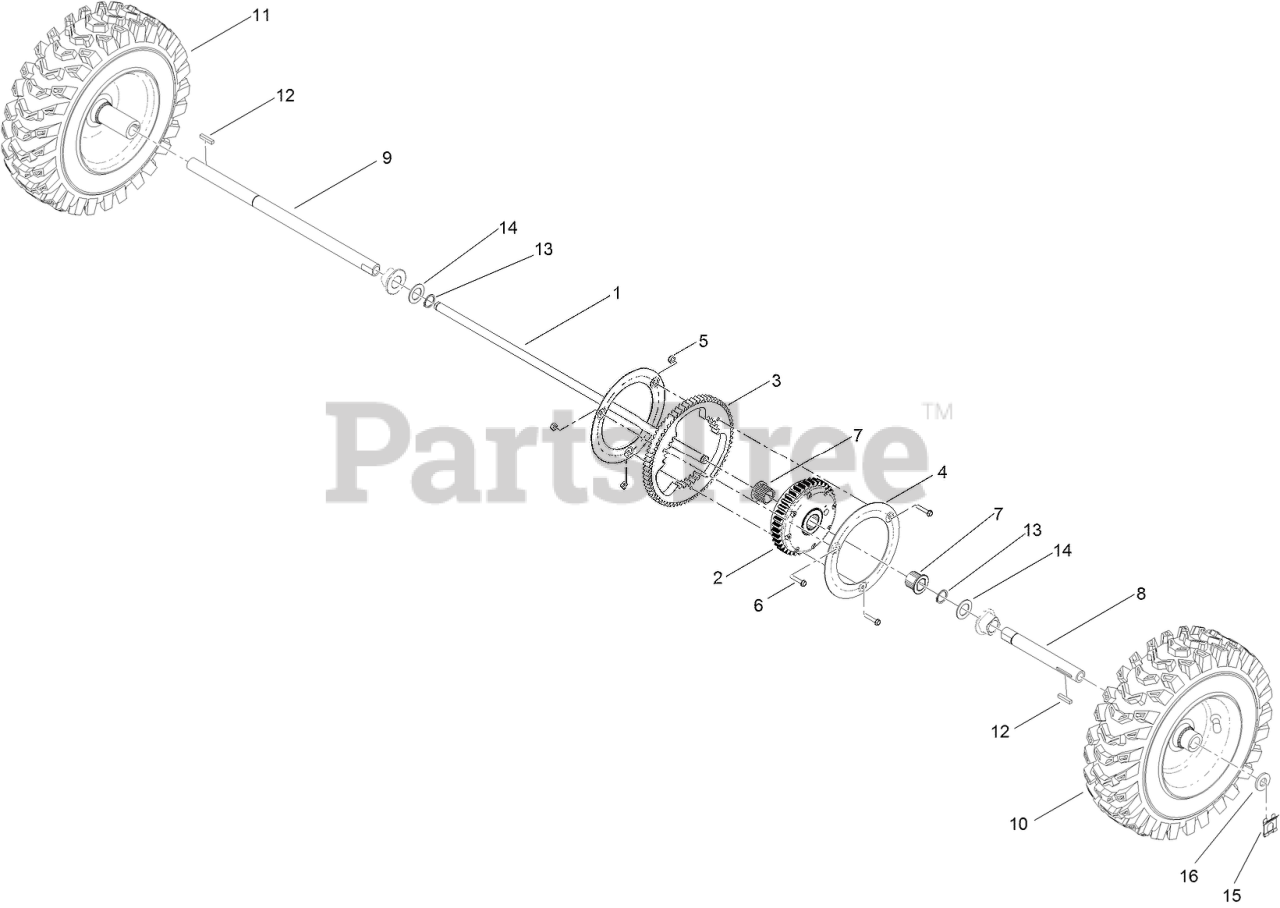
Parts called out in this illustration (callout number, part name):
2	TRANSMISSION
3	GEAR-AXLE
4	PLATE-GEAR
5	NUT-LOCK, NI
6	SCREW-HWH
7	GEAR-TUBE, AXLE
8	TUBE-AXLE
9	TUBE-AXLE
10	LH WHEEL AND TIRE ASM
11	RH WHEEL AND TIRE ASM
12	KEY-SQUARE
13	Ring-Snap
14	WASHER-THRUST
15	CLIP-PIN
16	WASHER-THRUST, PLAIN
